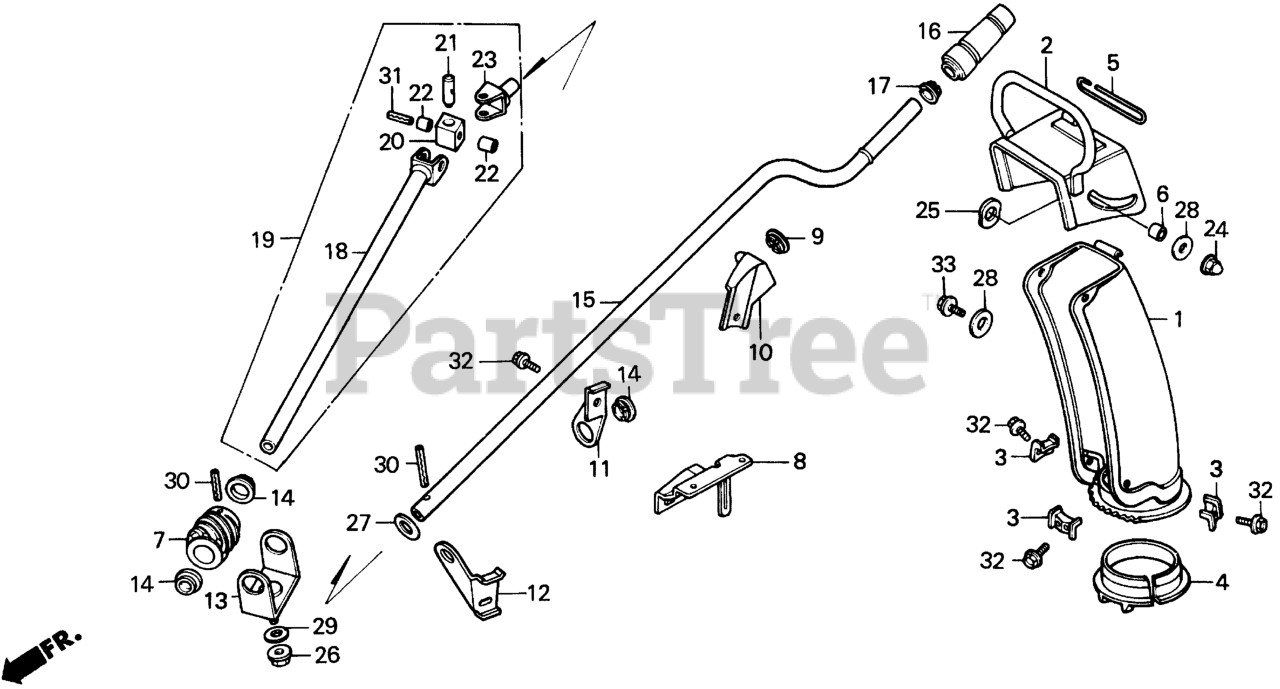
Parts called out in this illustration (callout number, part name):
1	CHUTE (NOT AVAILABLE)
2	GUIDE, CHUTE (NOT AVAILABLE)
3	PLATE, CHUTE SETTING (NOT AVAILABLE)
4	BUSH, CHUTE
5	PIN, CHUTE GUIDE
6	COLLAR, CHUTE GUIDE (NOT AVAILABLE)
7	GEAR, CHUTE DRIVE
8	HOLDER, HANDLE BRACKET
9	BUSH, CHUTE HANDLE
10	BRACKET A, CHUTE HANDLE (NOT AVAILABLE)
12	BRACKET B, CHUTE HANDLE
13	STAY, DRIVE GEAR
14	BUSH, DRIVE GEAR
15	HANDLE, CHUTE (UPPER)
16	GRIP, CHUTE HANDLE
17	BUSH A, CHUTE HANDLE
18	HANDLE, CHUTE (LOWER)
19	HANDLE, CHUTE (LOWER) (NOT AVAILABLE)
20	PIECE, JOINT
21	PIN A, JOINT
22	PIN B, JOINT
24	NUT, CAP (6MM)
25	SPRING, LEVER
26	NUT, FLANGE (8MM)
27	WASHER, PLAIN (16MM)
28	WASHER, PLAIN (6MM)
29	WASHER, PLAIN (8MM)
30	PIN, SPRING (4X28)
31	PIN, SPRING (4X32)
32	BOLT, FLANGE (6X12) Use up to Engine SN 1543277.
33	BOLT, FLANGE (6X14)
